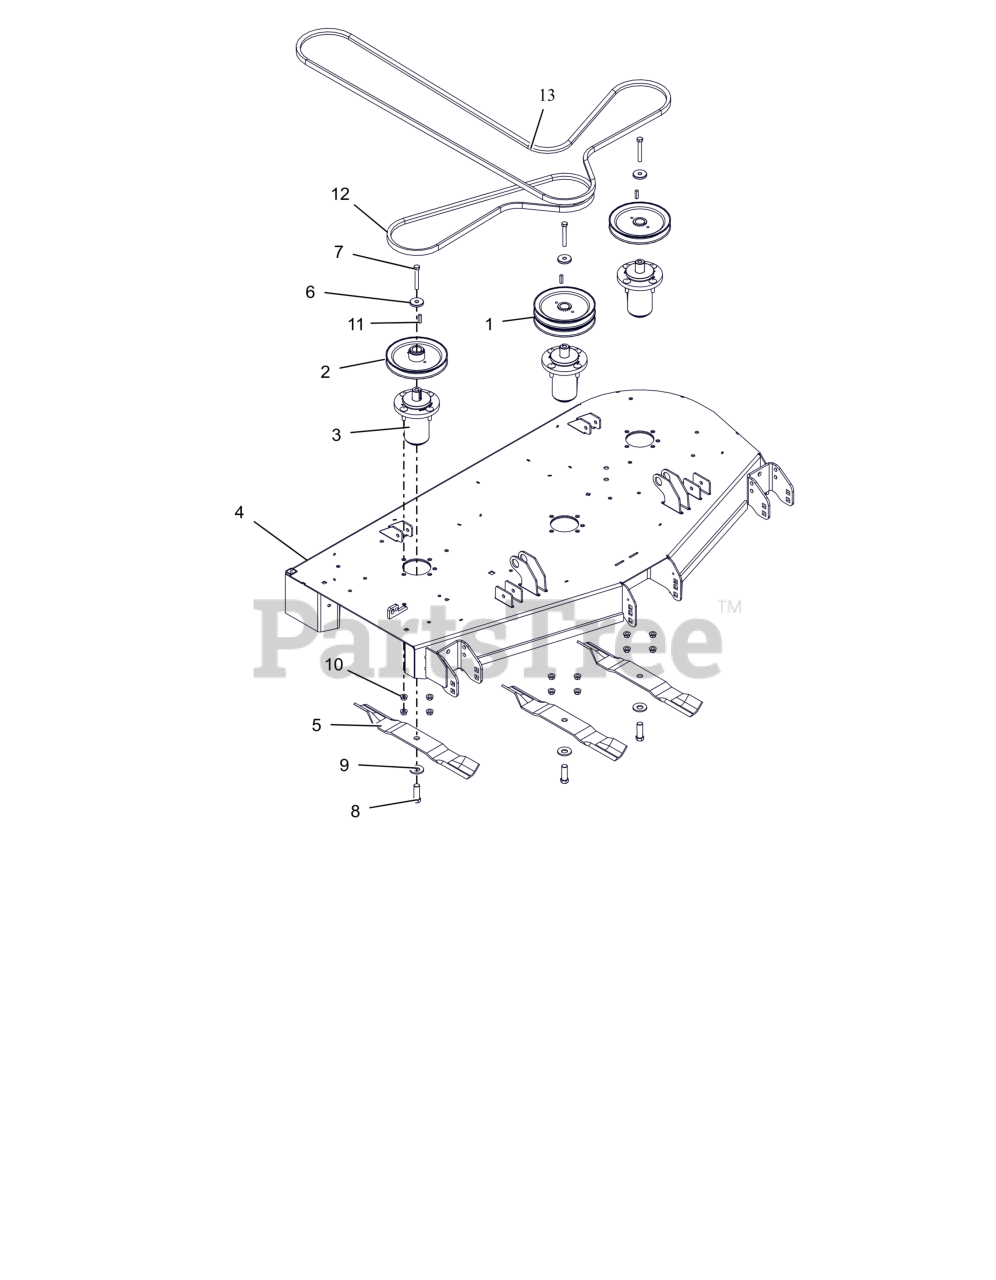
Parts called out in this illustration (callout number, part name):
1	PULLEY, DOUBLE-1"ID X 6.75"OD
2	PULLEY, V-1" ID X 6.75" OD
3	ASM, MAINT FREE ALUM SPINDLE
4	KIT,DECK-52" W/DECALS - ARIENS
5	BLADE, 18"
6	RETAINER, SHEAVE
7	BLT, HEX .38-16X2.75 G8 ZCC
8	BLT, HEX .62-18X1.75 G8 ZCC
9	WSHR-BLVL .669X1.535X.138
10	NUT-LK-CTR-FLG .375-16 GF ZCC
11	KEY, SQ .25X.25X1.00 RC 40-50
12	V-BELT, B-COGGED
13	V-BELT, HB SECTION
